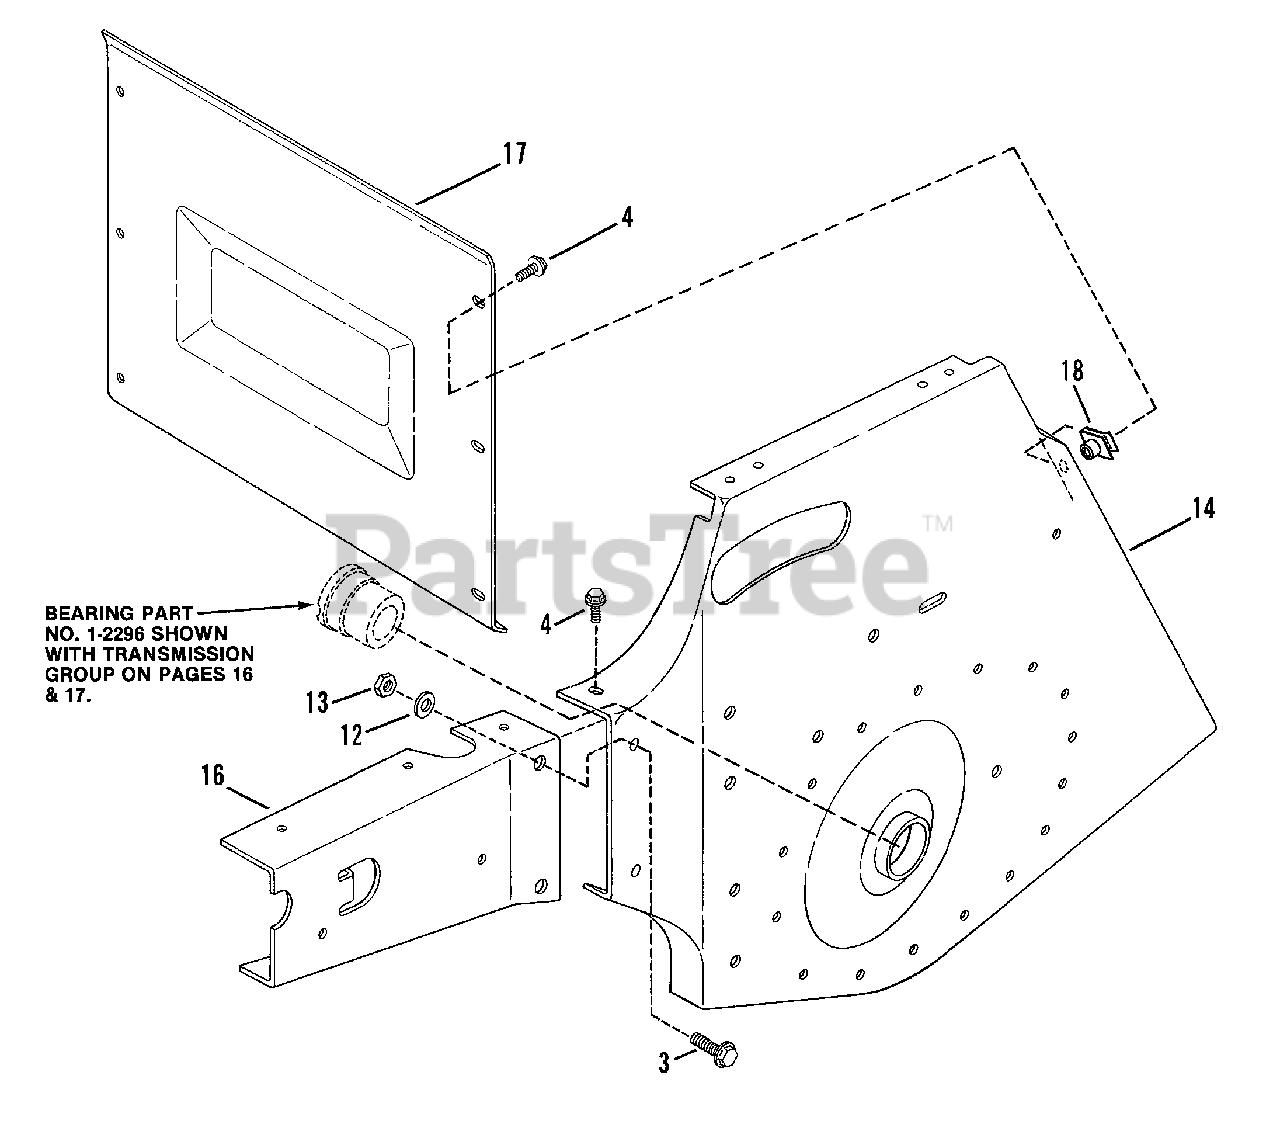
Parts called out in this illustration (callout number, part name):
3	BOLT, 3/8-16 x 1" Hex Flange Lock
4	SCREW, 5/16-18 x 5/8" Self-Tapping
12	WASHER, 3/8 SAE
13	NUT, 3/8-16 Center Lock
14	TRANSMISSION SUPPORT, L.H.
16	EXTENSION, Transmission Support, L.H.
17	COVER, Rear
18	NUT, 5/16 Push-on
